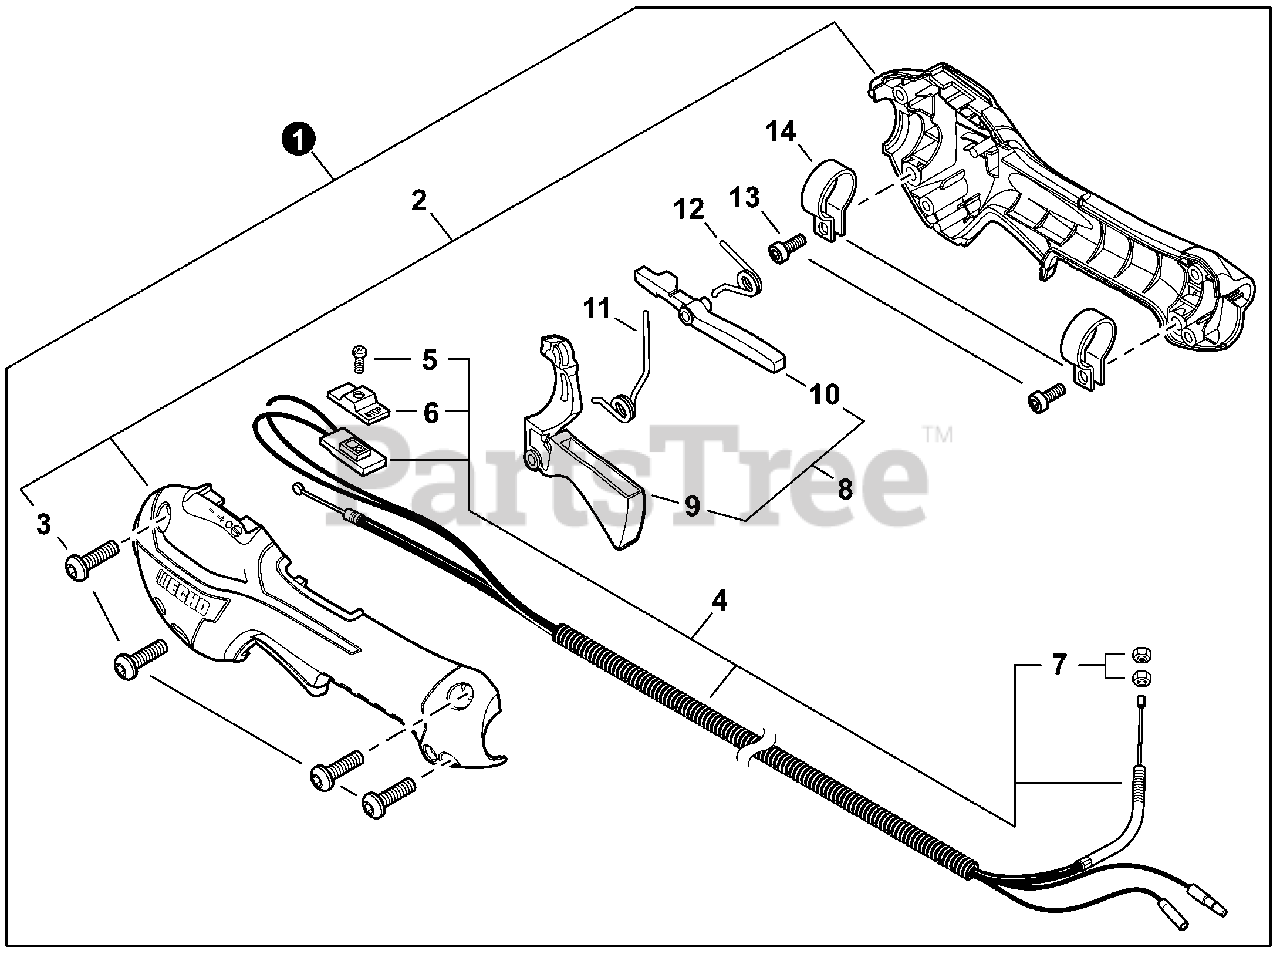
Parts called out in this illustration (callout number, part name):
1	CONTROL HANDLE ASSY
2	CONTROL HANDLE KIT
3	BOLT, TORX 5×16
4	CABLE ASSY, CONTROL
5	SCREW 3×10
6	KNOB, SWITCH - ORANGE
8	THROTTLE LOCKOUT KIT
9	TRIGGER, THROTTLE
10	LEVER, THROTTLE LOCKOUT
11	SPRING, TORSION
12	SPRING, TORSION
13	BOLT, TORX 5×16
